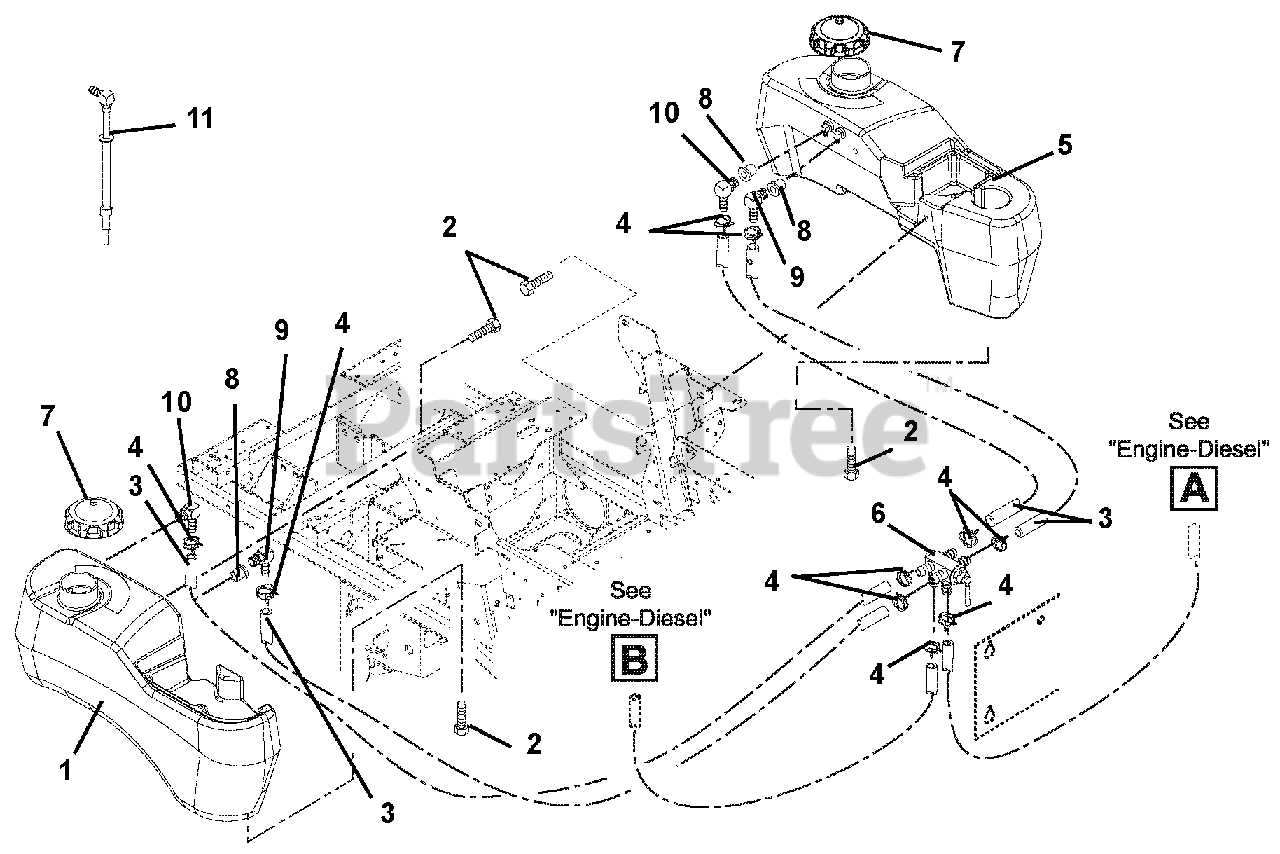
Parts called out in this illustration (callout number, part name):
1	TANK, RH FUEL
2	BOLT, SEMS .31-18 X .62
3	HOSE,5/16 ID
4	CLAMP, HOSE WIRE .520/.550
5	TANK, LH FUEL
6	VALVE, FUEL
7	CAP, FUEL
8	GROMMET, DAPCO VITON #12240
9	FITTING, TANK ELBOW .31 HOSE
10	FITTING, TANK (5/16 ELBOW)
11	26" FUEL LINE KIT-DIESEL & EFI
